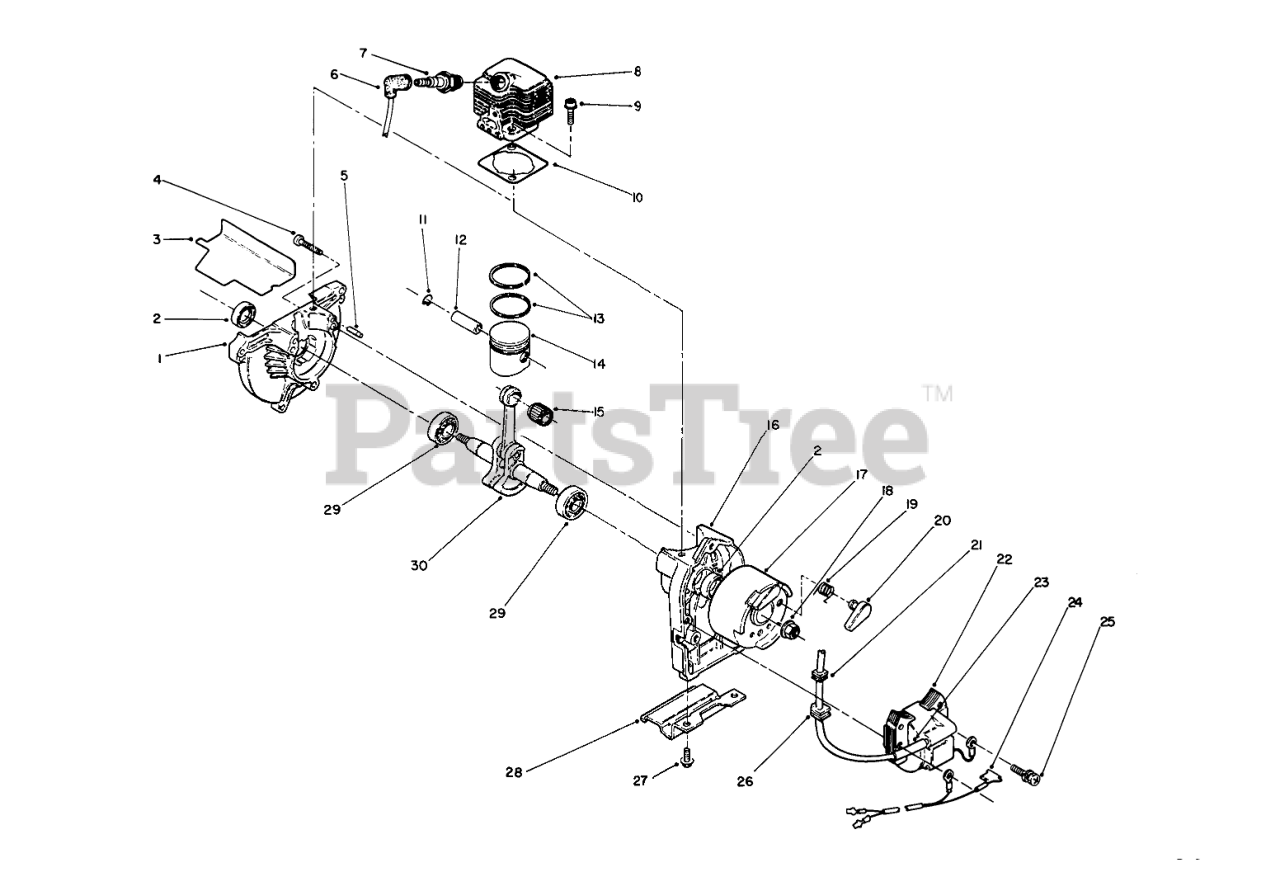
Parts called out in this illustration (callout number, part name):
1	DRIVE CASE
2	OIL SEAL
3	BAFFLE GASKET
4	Screw
6	PLUG BOOT
7	SPARK PLUG (NGK)
8	CYCLINDER
10	Gasket-Cylinder Head
11	CLIP, PISTON PIN
12	PIN, PISTON
13	RING,PISTON
14	Piston Assembly (Incl. Ref. #12)
15	BEARING, NEEDLE
16	STARTER CASE
17	Flywheel Assembly (Incl. Ref. #19 & 20)
19	RETURN SPRING
20	RATCHET
21	GROMMET
22	IGNITION COIL
24	LEAD WIRE
25	BOLT AND WASHER
26	GROMMET
27	SCREW & WASHER
28	STAND SUPPORT
29	BEARING
30	Crankshaft Assembly
